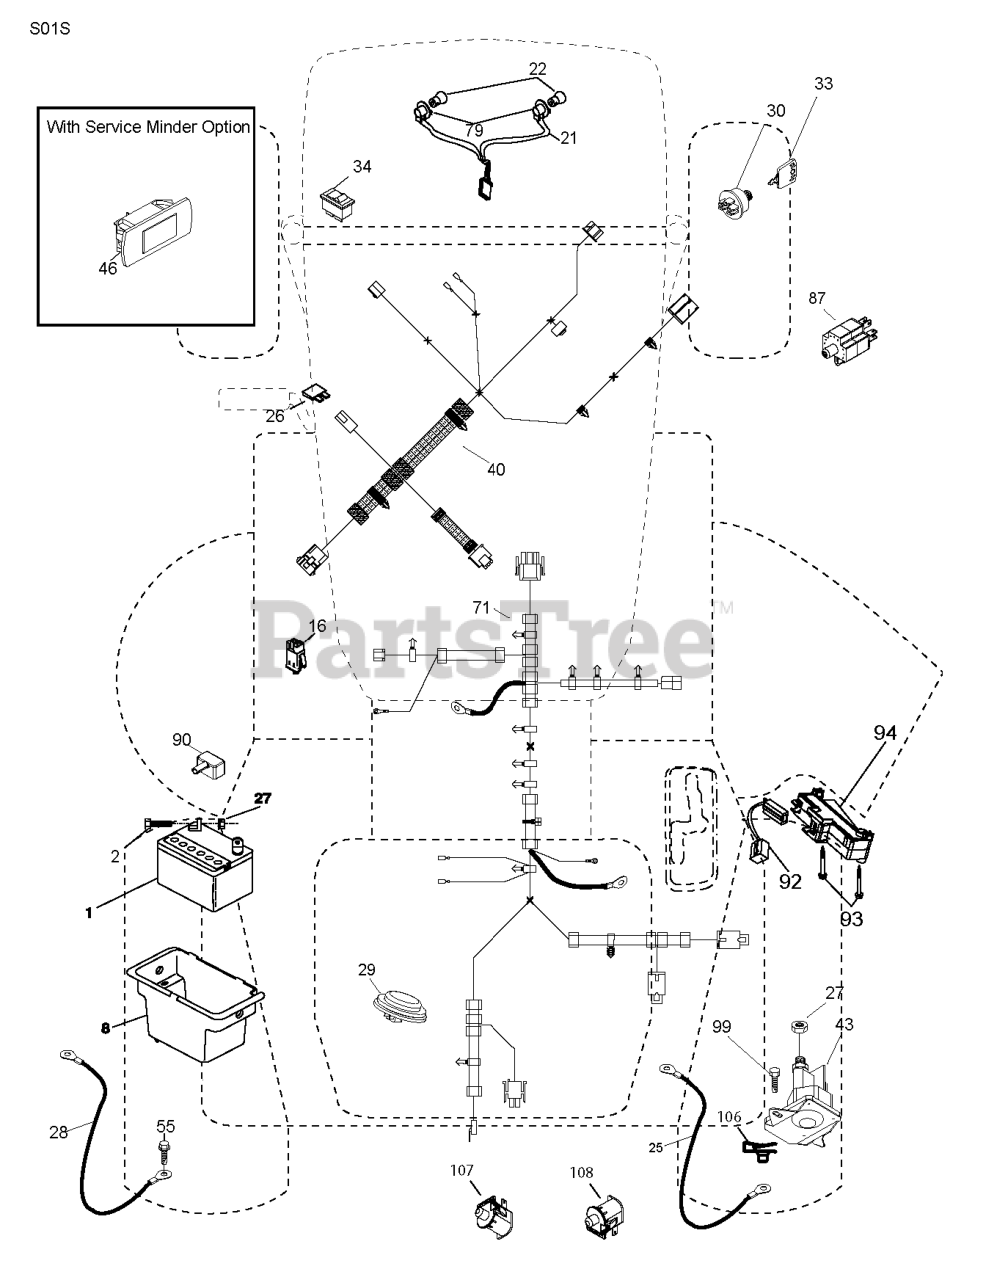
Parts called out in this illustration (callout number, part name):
1	REPL BY 532 12 38-99
2	BOLT.HEX.1/4.X.3/4.DICHROMATE
8	BOX.BATTERY.LT/SRD
16	SWITCH INTERLOOK PUSH-IN
21	HARNESS.LIGHT W/4152J BULBS
25	CABLE.BATTERY.20.RED.8 AWG
26	FUSE 20AMP
27	NUT
28	CABLE.GROUND.REAR.BATTERY.8G
29	SWITCH.SEAT.DELTA.OPC.
30	SWITCH.IGN.DELTA.W.LGH.ROS
33	KEY.CHAIN.BLISTER.PACK.GEN.INT
40	RP HARNESS.ELECTRICAL.DASH.SRD
43	SOLENOID.W/BRASS.PLUNGER
55	SCREW 5/16"
71	RP.HARNESS.ELEC.CHASSIS.SRD
79	BULB HOLDER ASM.
87	RP SWITCH.RAILMOUNT.NO-NC-NC
90	COVER, TERMINAL BATTERY
92	HARNESS.PIGTAIL.CONSLE
93	SCREW.PLASTITE
94	MODULE.REVERSE.ROS
99	SCREW HEXWSHR 1/4-20X3/4
106	1/4-20 U NUT
107	SWITCH.SNAPMOUNT.NO.#2
108	SWITCH.SNAPMOUNT.NC
